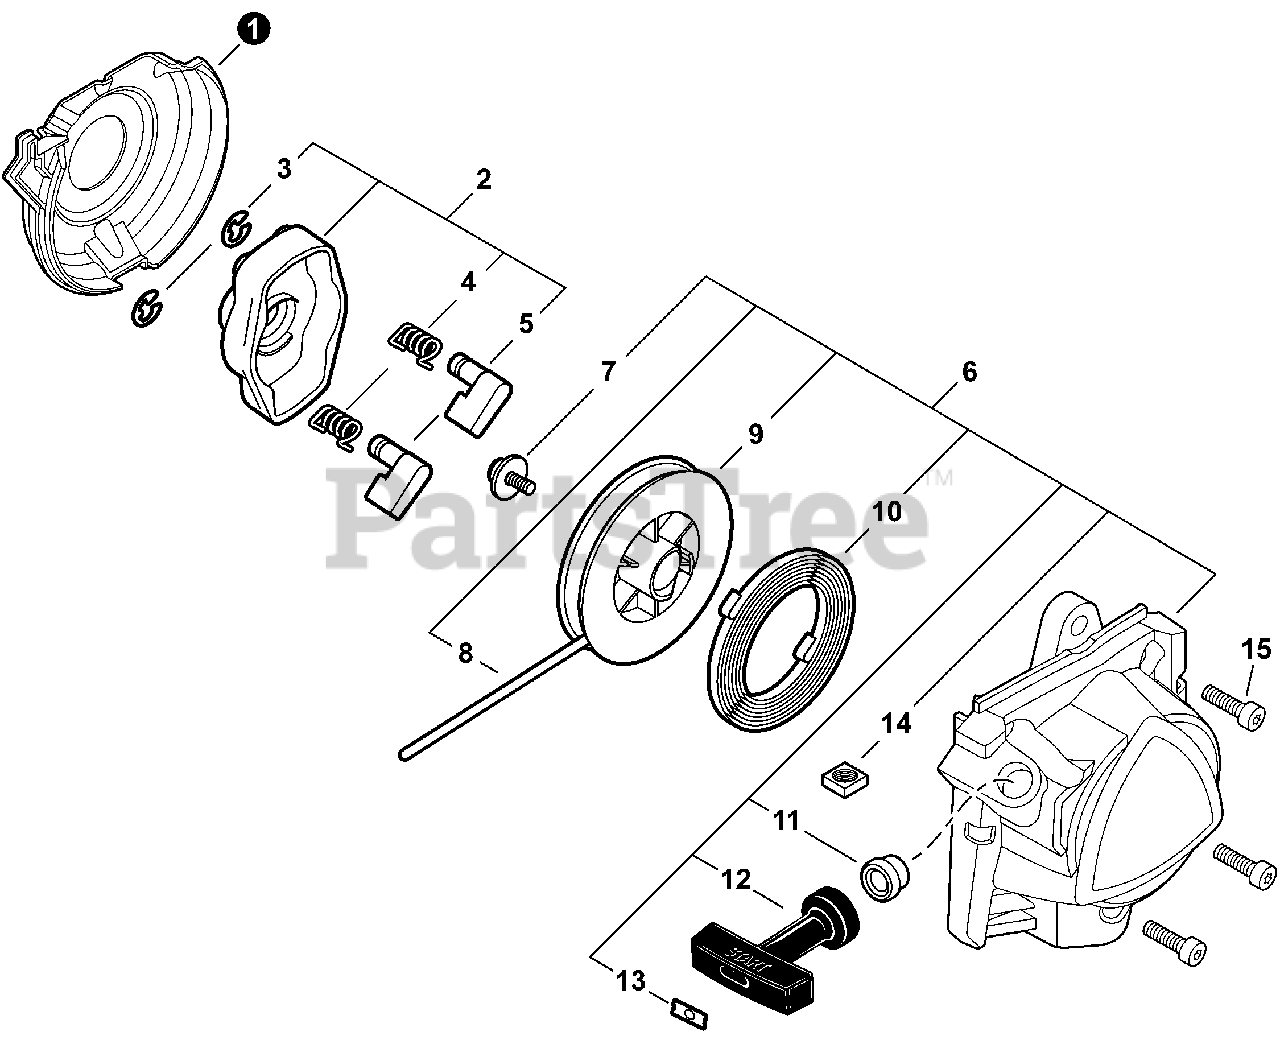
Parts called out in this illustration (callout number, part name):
1	COVER, DUST
2	PAWL ASSY, STARTER
3	E-RING 4
4	SPRING, RETURN
5	PAWL, STARTER
6	STARTER ASSY, RECOIL
7	SCREW
8	ROPE, STARTER
9	REEL, ROPE
10	SPRING, RECOIL
11	GUIDE, ROPE
12	GRIP, STARTER
13	RETAINER, ROPE
14	NUT M5
15	BOLT, TORX 5×12
